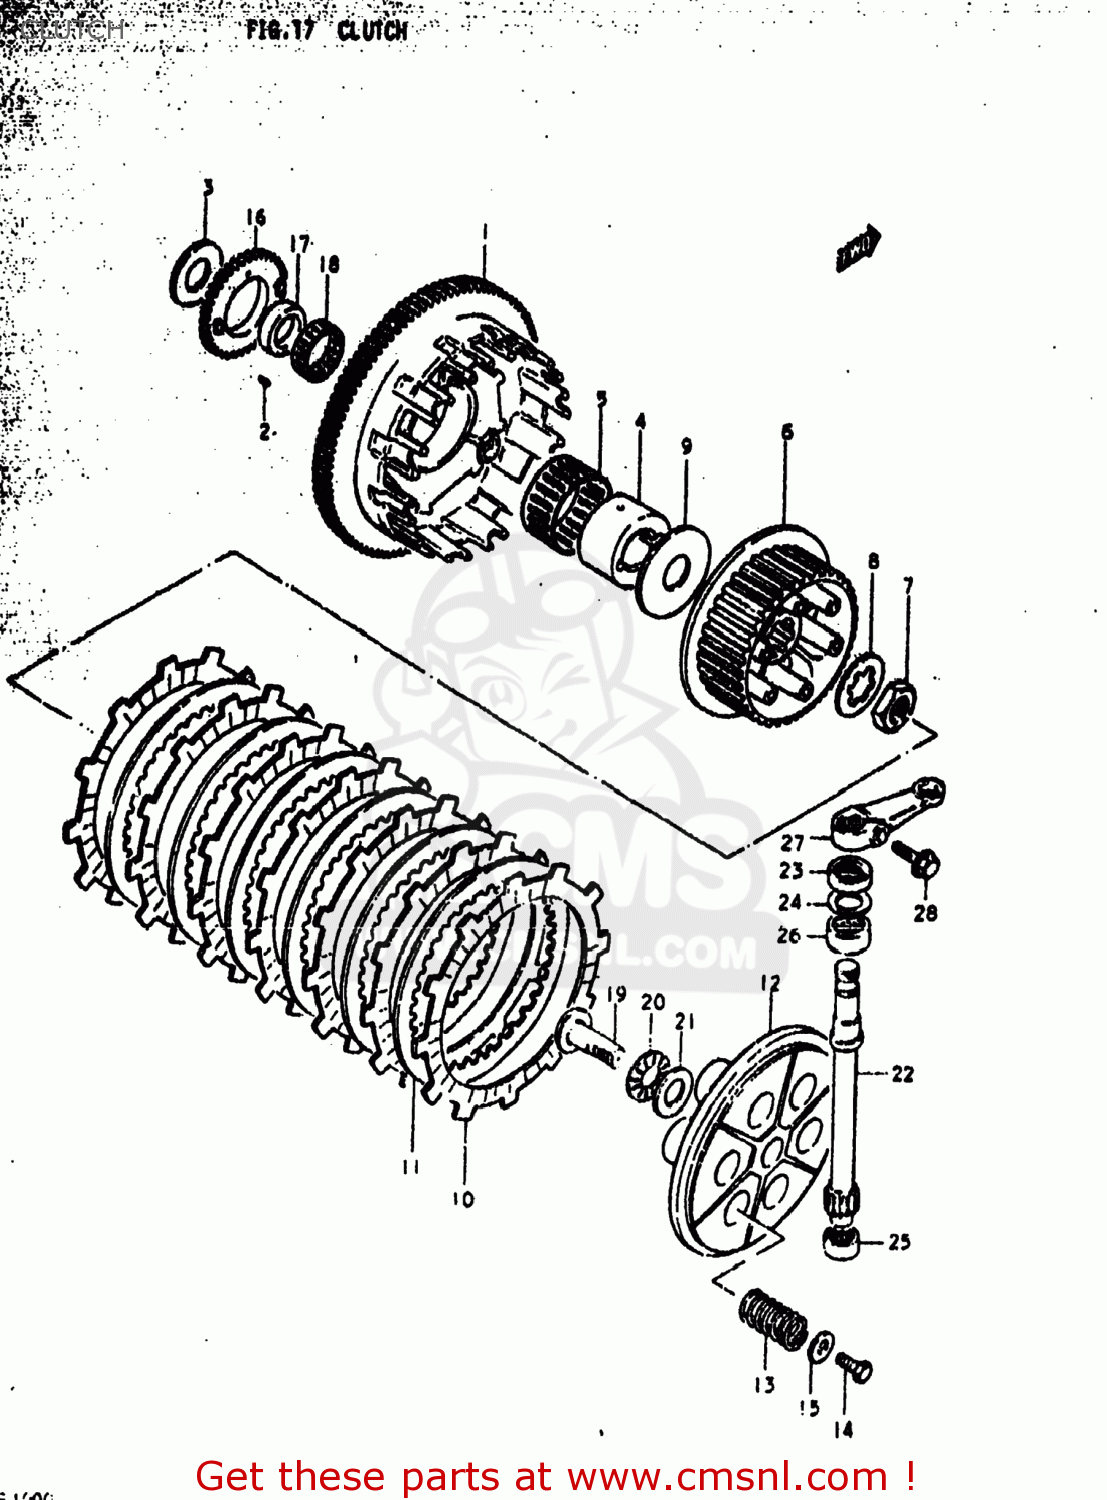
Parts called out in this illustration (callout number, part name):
1	GEAR ASSEMBLY,PRIMARY DRIVE
2	CUSHION,PRIMARY DRIVEN GEAR
3	WASHER
4	SPACER,PRIMARY DRIVEN
5	BEARING
6	HUB,CLUTCH SLEEVE
7	NUT
8	WASHER,LOCK
9	WASHER(25X66X3.5)
10	PLATE,CLUTCH DRIVE (MCA)
11	PLATE,CLUTCH DRIVEN (NAS)
12	DISC,CLUTCH PRESSURE
13	SPRING
14	BOLT, UPPER
15	WASHER
16	GEAR,OIL PUMP DRIVE
17	SPACER,OIL PUMP DRIVE GEAR
18	BEARING(36X40X10)
19	RACK,CLUTCH RELEASE
20	BEARING(15X28X2)
21	WASHER
22	PINION,CLUTCH RELEASE
23	OIL SEAL
24	WASHER (14.2X22X1)
25	BEARING(12X19X12)
26	BEARING(15X22X12)
27	ARM,CLUTCH RELEASE
28	BOLT
